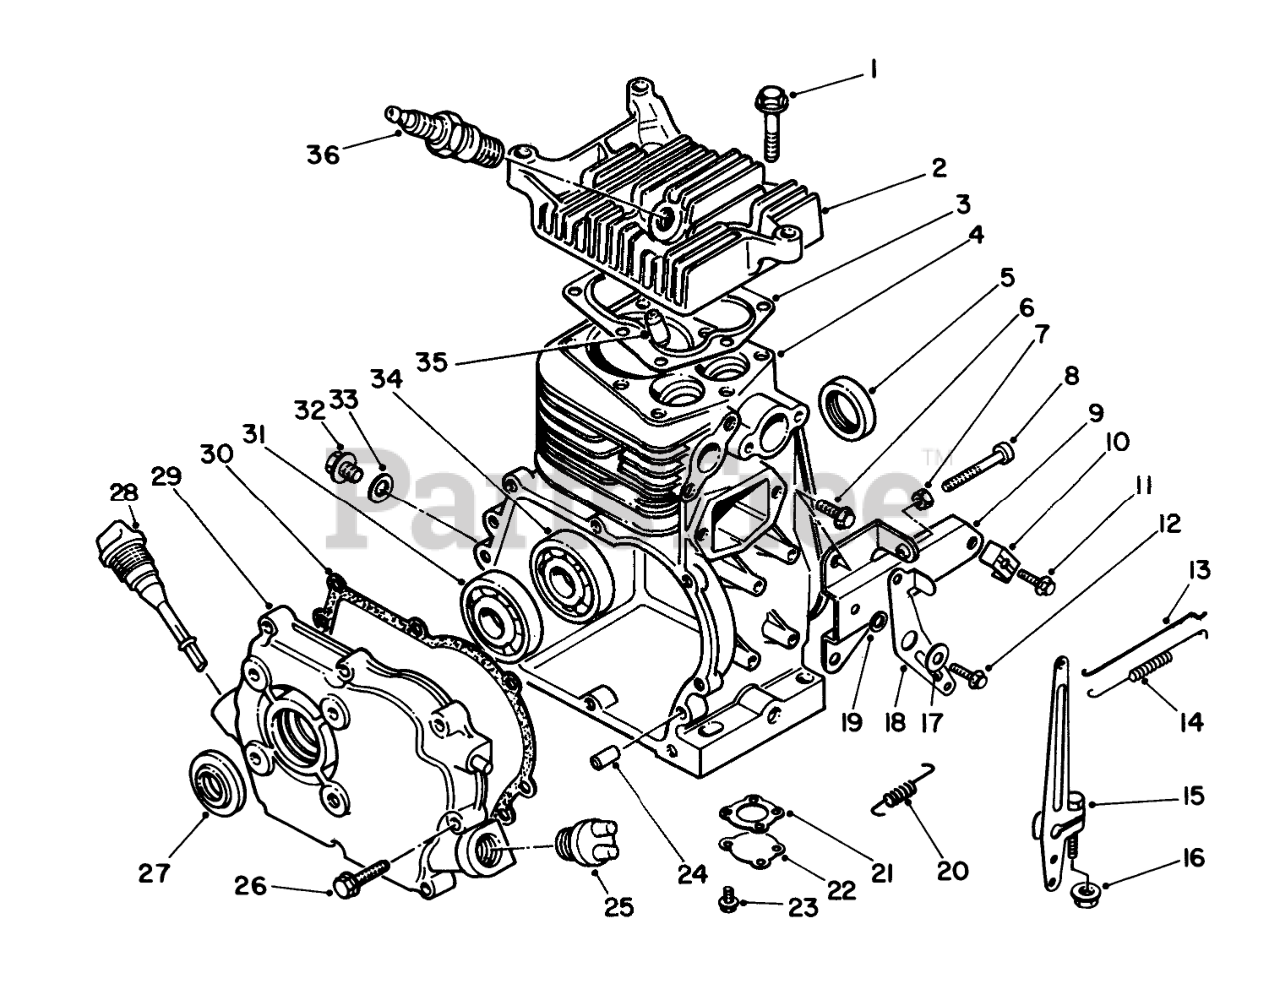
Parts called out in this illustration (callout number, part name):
2	Cylinder Head
3	GASKET
4	Cylinder
5	Oil Seal
8	Screw-Round Phillips Hd.
9	Bracket-Governor Control
10	CLAMP-CABLE
13	Rod-Carburetor
14	SPRING
15	Lever-Control
17	WASHER
18	Lever-Governor Control
19	Washer
20	Spring
21	GASKET
22	Cover-Level Sensor
27	Oil Seal
28	Gauge-Oil Level
29	Cover-Crankcase Side
30	Gasket-Crankcase
31	Bearing
32	Drain Plug
33	GASKET
34	Bearing
35	Guide Valve
36	SPARK PLUG
